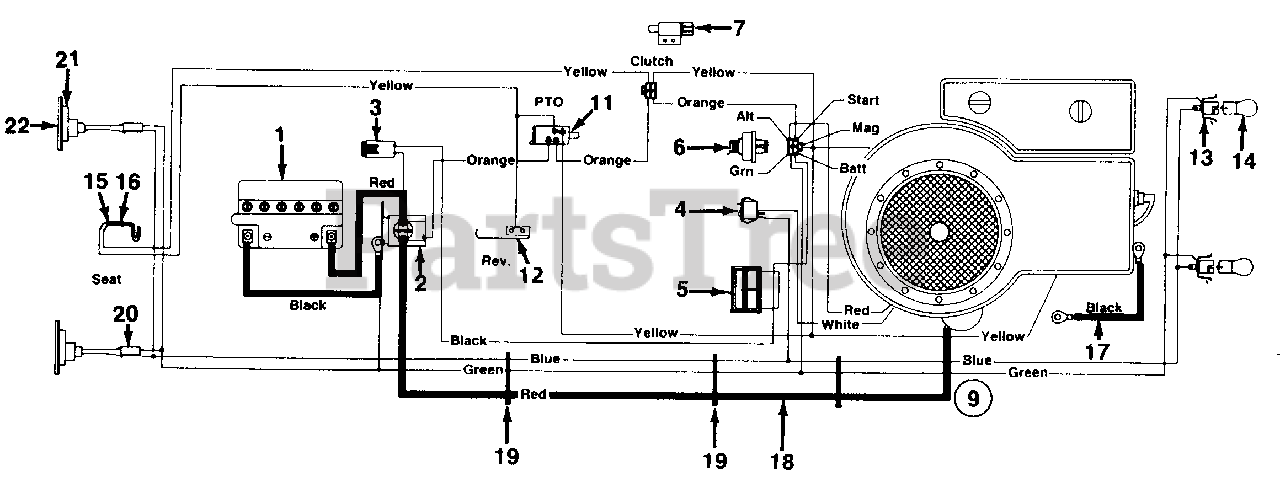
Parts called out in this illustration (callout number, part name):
1	Battery
2	Solenoid
3	Fuse 7.5 Amp
4	Light Switch
5	Ammeter
6	Ignition Switch
7	Safety Switch (Clutch)
9	Wire Harness
11	Safety Switch (Deck)
12	Safety Switch (Reverse)
13	Socket
14	Bulb
15	Safety-Switch (Seat)
16	Safety Switch (Seat)
17	Ground Wire 7.5" Lg.
18	Electric Wire
19	Cable Tie
20	Taillight Harness
21	Taillight Lens
22	Taillight Bulb
